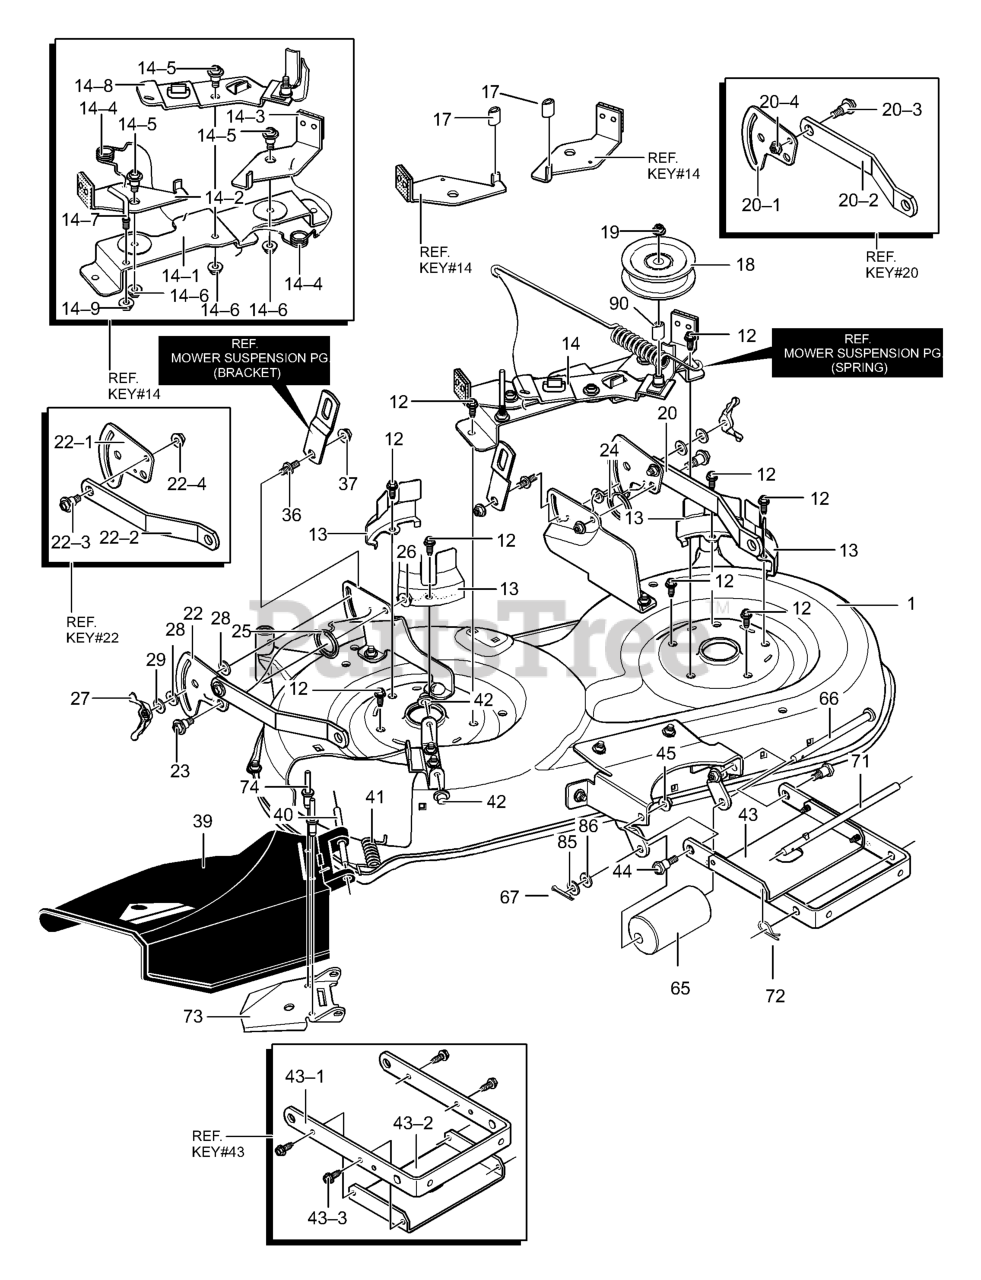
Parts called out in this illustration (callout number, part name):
1	ASSEMBLY, 42" MOWER DECK
12	BOLT
13	COVER, BELT GUIDE
14	ASM., BRKT SUP W/BRAKES
14-1	BRACKET, BRAKE MTG.
14-2	ASSY., BRAKE RH
14-3	ASSY., BRAKE LH
14-4	TORSION SPRING
14-5	BOLT, 3/8-16
14-6	NUT, .38-16
14-7	SCREW GUIDE
14-8	ASSY., IDLER ARM
14-9	NUT, .32-18
17	TUBE, BRAKE TAB PAD
18	PULLEY, IDLER
19	NUT, 3/8-16
20	PLATE ASM., LH REAR SUSP
20-1	PLATE-SUSPENSION
20-2	SUSPENSION BRACKET REAR
20-3	BOLT, SHOULDER
20-4	NUT, 3/8-16
22	PLATE ASM., RH REAR SUSP
22-1	PLATE-SUSPENSION
22-2	SUSPENSION BRACKET REAR
22-3	BOLT, SHOULDER
22-4	NUT, 3/8-16
23	BOLT, SHOULDER
24	SPRING,TORSION
25	SPRING,TORSION
27	WINGNUT, 5/16-18
28	PAD, FRICTION
29	WASHER
36	PIN, HANGER
39	DEFLECTOR CHUTE
40	ROD, CHUTE DEFLECT
41	SPRING - TORSSION
42	NUT, PUSH CAP
43	ASM. BRKT. & STIFFENER
43-1	BRACKET, SUSPENSION
43-2	STIFFENER
43-3	SCREW, 5/16-18 x 0.75
44	BOLT, SHOULDER
66	ROD,SUPPORT
67	PIN, COTTER
71	ROD, HANGER
72	PIN, HAIR
73	DEFLECTOR SUPPORT
74	RIVET-SEMI
85	WASHER, FLAT
86	WASHER, WAVE
90	SPACER 1/2 TO 17MM
